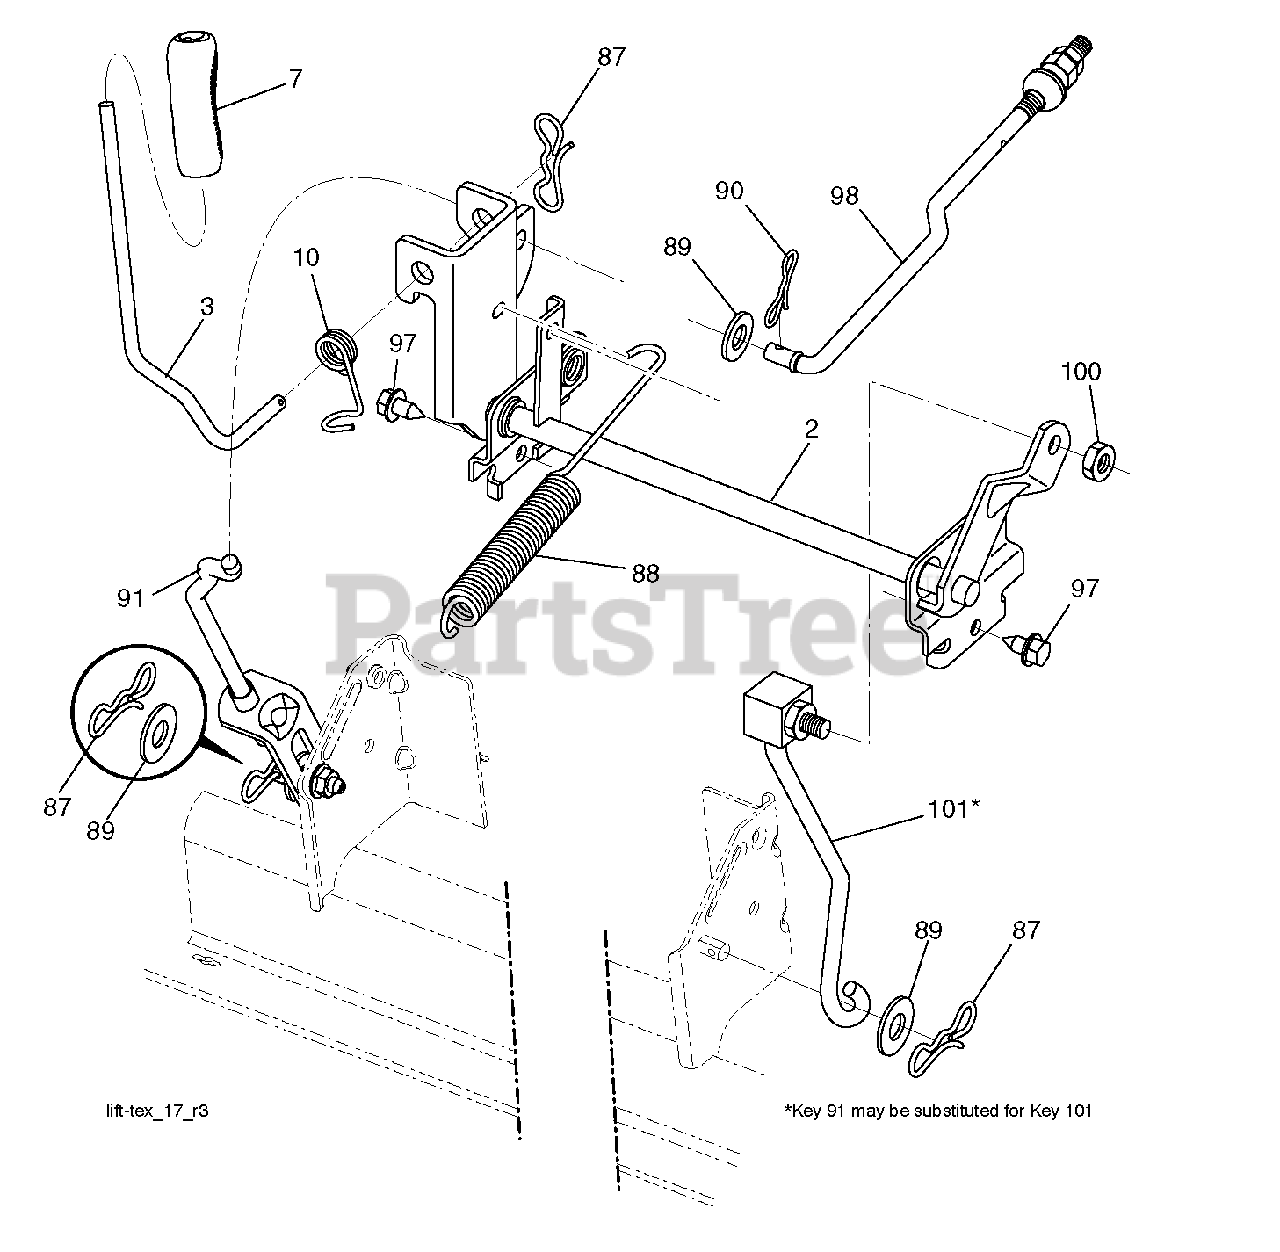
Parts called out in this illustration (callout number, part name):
2	SHAFT.ASM.CROSS.LIFT
3	LEVER.LIFT.HANDLE.LT
7	GRIP.HANDLE.LIFT.PVC.BLACK
10	SPRING.TORSION.LIFT.HANDLE
87	PIN.COTTER.7/16.BOW TI.
88	SPRING.LIFT.ASSIST
89	WASHER.CLEAR.ZINC
90	PIN.COTTER.5/16.BOW TI
91	LINK.ASM.LIFT.REAR
97	SCREW, 3/8-16X3/4
98	LINK.ASM.SUSP.FRONT.MW
100	LOCKNUT
101	LINK.ASM.LIFT.FIXE.38/42/46"
